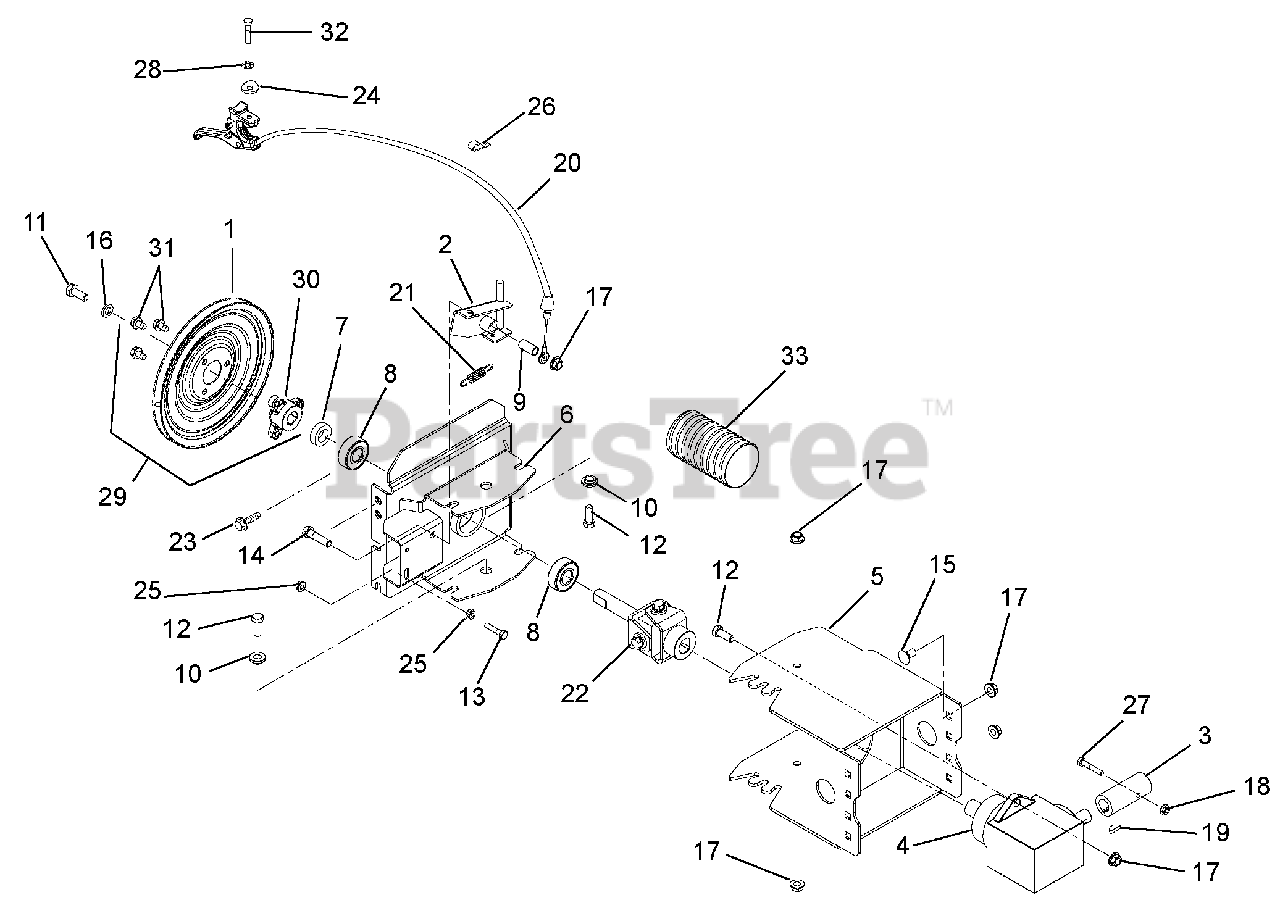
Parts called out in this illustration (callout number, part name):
1	PULLEY,SPIN FORM SINGLE GROOVE
2	ARM, PIVOT LOCK
3	HUB, COUPLING
4	GEAR BOX ASSEMBLY
5	ADAPTER WITH DECAL,BRUSH FRAME
5	DECAL, PTO WARNING
6	ADAPTER, FRAME-20000 SERIES
7	SPACER .755X1.250X.370
8	BRG-BALL .750X1.781X.61
9	BSHG-SLV .385X.500X1.045
10	BSHG-FLG .406X.88X.270X.140
11	BLT-HEX .31-24X.75 YWZC GR5
12	@BLT-HEX .38-16X1.00 GR5 YWZC
13	@BLT-HEX .25-20X1.50 GR5 YWZC
14	@BLT-HEX .38-16X1.75 GR5 YWZC
15	@BLT-RDHDSQNK .38-16X.75 G5YZ
16	WSHR-LK .312X.097 HVY YWZC
17	@NUT-LK-TOP-FLG .38-16 YWZC
18	@NUT-LK-TOP-FLG .25-20 YWZC
19	KEY-WDRF .188X.75X.313 SAE 9
20	CABLE, REMOTE BRUSH LOCK
21	SG-TENS .06X.46X2.00
22	U-JOINT ASSY
23	@SCR-TAP .31-18X.75 HWH TR YWZ
24	SPACER, HANDLEBAR
25	@NUT-SPNLK-FLG .25-20 YWZC
26	J-CLAMP
27	@BLT-HEX .25-20X1.75 GR5 YWZC
28	WSHR-LK-INT .250 TH TYA
29	PULLEY WITH HUB
30	PULLEY HUB, BOLT-ON D-BORE .75
31	@SCR-TAP .31-18X.50 HWH TR YWZ
32	SCR-MCH .25-20X1.50 OVAL HD
33	HOSE 4" X 7" FLEX TUBE PV
